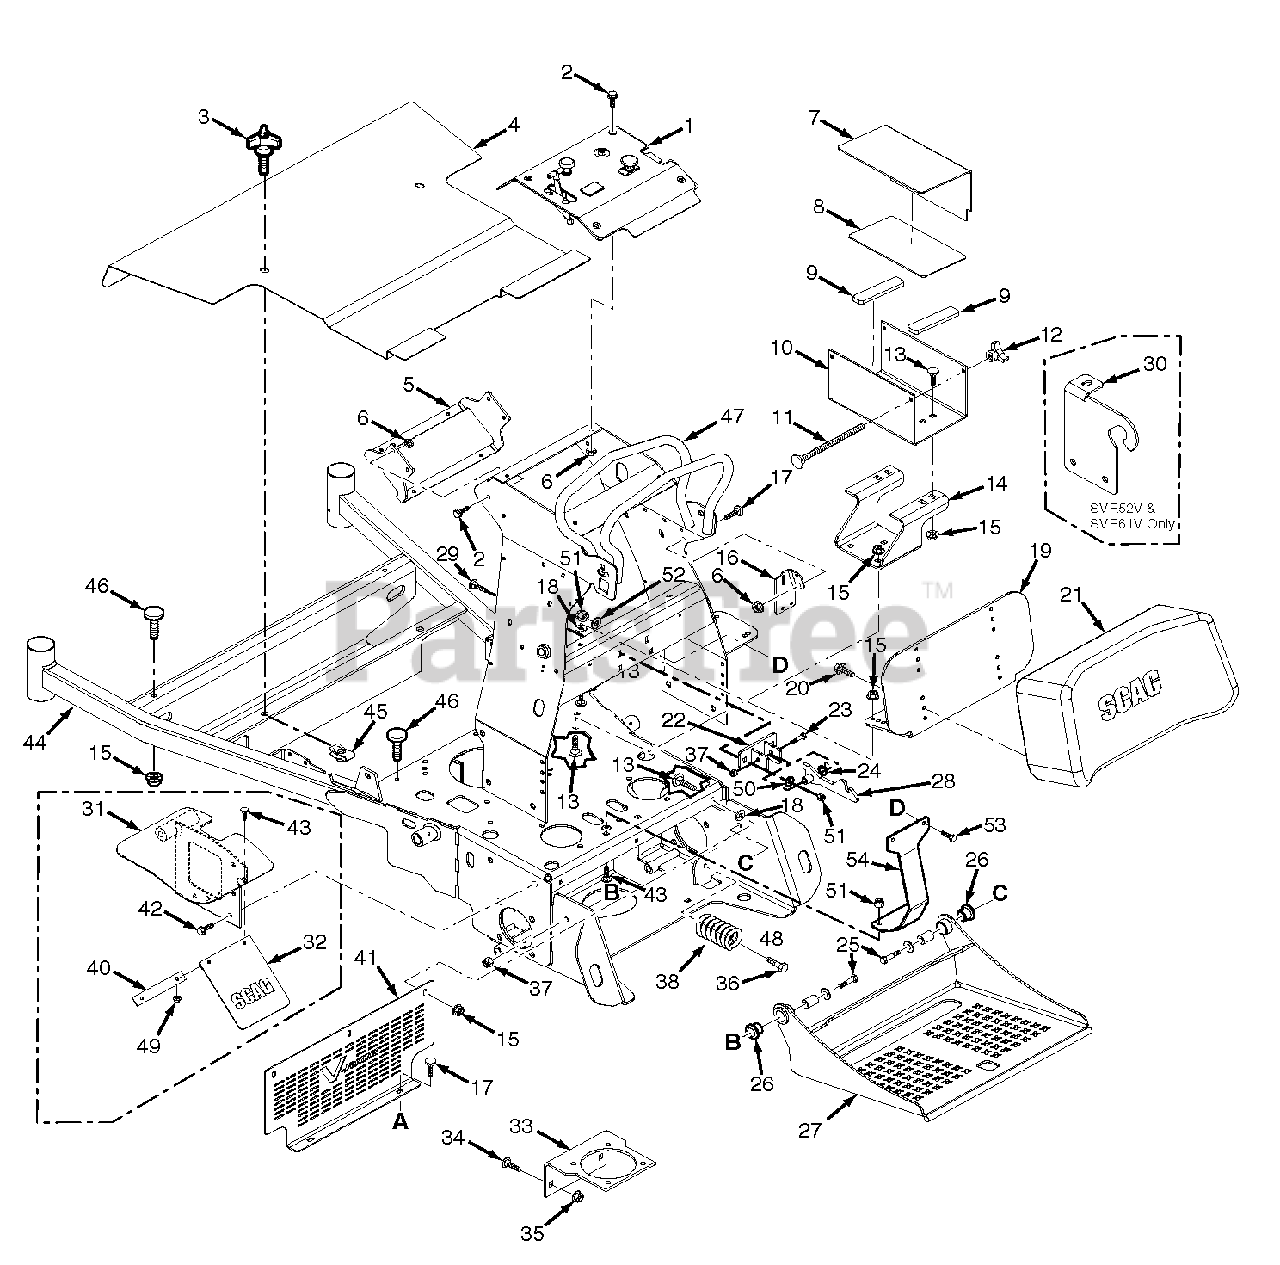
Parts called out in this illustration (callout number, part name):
1	Instrument Panel w/Decal
1	Instrument Panel w/Decal - EFI
2	Bolt, Hex Head 1/4-20 x .63
3	Knob w/Stud
4	Belt Cover w/Decals - 36
4	Belt Cover w/ Decals - 48
4	Belt Cover w/ Decals - 52
4	Belt Cover w/Decals - 61
5	Bracket, Oil Cooler - 48 / 52
5	Bracket, Oil Cooler - 61
5	Bracket, Oil Cooler - EFI
6	Nut, Serrated Flange 1/4-20
7	Battery Cover
8	Insulation, Battery Cover
9	Pad, Rubber
10	Battery Box
11	Bolt, Carriage 1/4-20 x 6"
12	Wing Nut, 1/4-20
13	Bolt, Carriage 5/16-18 x 3/4"
14	Bracket, Battery Support
15	Nut, Serrated Flange 5/16-18
16	Bracket, Neutral Switch
17	Bolt, Carriage 1/4-20 x 3/4"
18	Nut, Push On 5/16"
19	Bracket, Knee Pad
20	Bolt, Hex Head 1/4-20 x 3/4"
21	Knee Pad
22	Latch Assembly
22	Mounting Bracket Weldment, Latch
23	Bolt, Hex Head 3/8-16 x 2-1/4"
24	Spring, Latch
25	Bolt, Hex Head 3/8-16 x 2"
26	Bearing
27	Footplate Assembly - 36
27	Footplate Assembly - 48
27	Footplate Assembly - 52 / 61
28	Latch Weldment
29	Bolt, Carriage 5/16-18 x 1"
30	Brake Shaft Support (52 / 61 only)
31	Fender Weldment (52 / 61 only)
32	Mudflap (52 / 61 only)
33	Bracket, Oil Filter Base
34	Bolt, Hex Head 3/8-16 x 1"
35	Nut, Serrated Flange 3/8-16
36	Bolt, Hex Head 3/8-16 x 1-3/4"
37	Nut, Elastic Stop 3/8-16
38	Spring, Foot Platform
39	Pin, Spring Mount
40	Strap, Mudflap (52 / 61 only)
41	Guard, Foot - 36
41	Guard, Foot - 48
41	Guard, Foot - 52 / 61
42	Bolt, Hex Head 3/8-16 x 1"
43	Bolt, Carriage 5/16-18 x 3/4"
44	Mainframe Assembly w/Decals - 36
44	Mainframe Assembly w/Decals - 48
44	Mainframe Assembly w/Decals - 52
44	Mainframe Assembly w/Decals - 61
45	U-Nut, 3/8-16
46	Bumper, Rubber
47	Handle Weldment - 36
47	Handle Weldment - 48
47	Handle Weldment - 52 / 61
48	Bolt, Hex Head 3/8-16 x 1-1/4"
49	Nut, Center Lock 5/16-18 (61 only)
50	Flatwasher, 5/16-.344 x .688 x .065
51	Nut, Elastic Stop 5/16-18
52	Flatwasher, 5/16-.375 x .875 x .083
53	Bolt, Hex Head 5/16-18 x 3/4"
54	Brace, Handle
